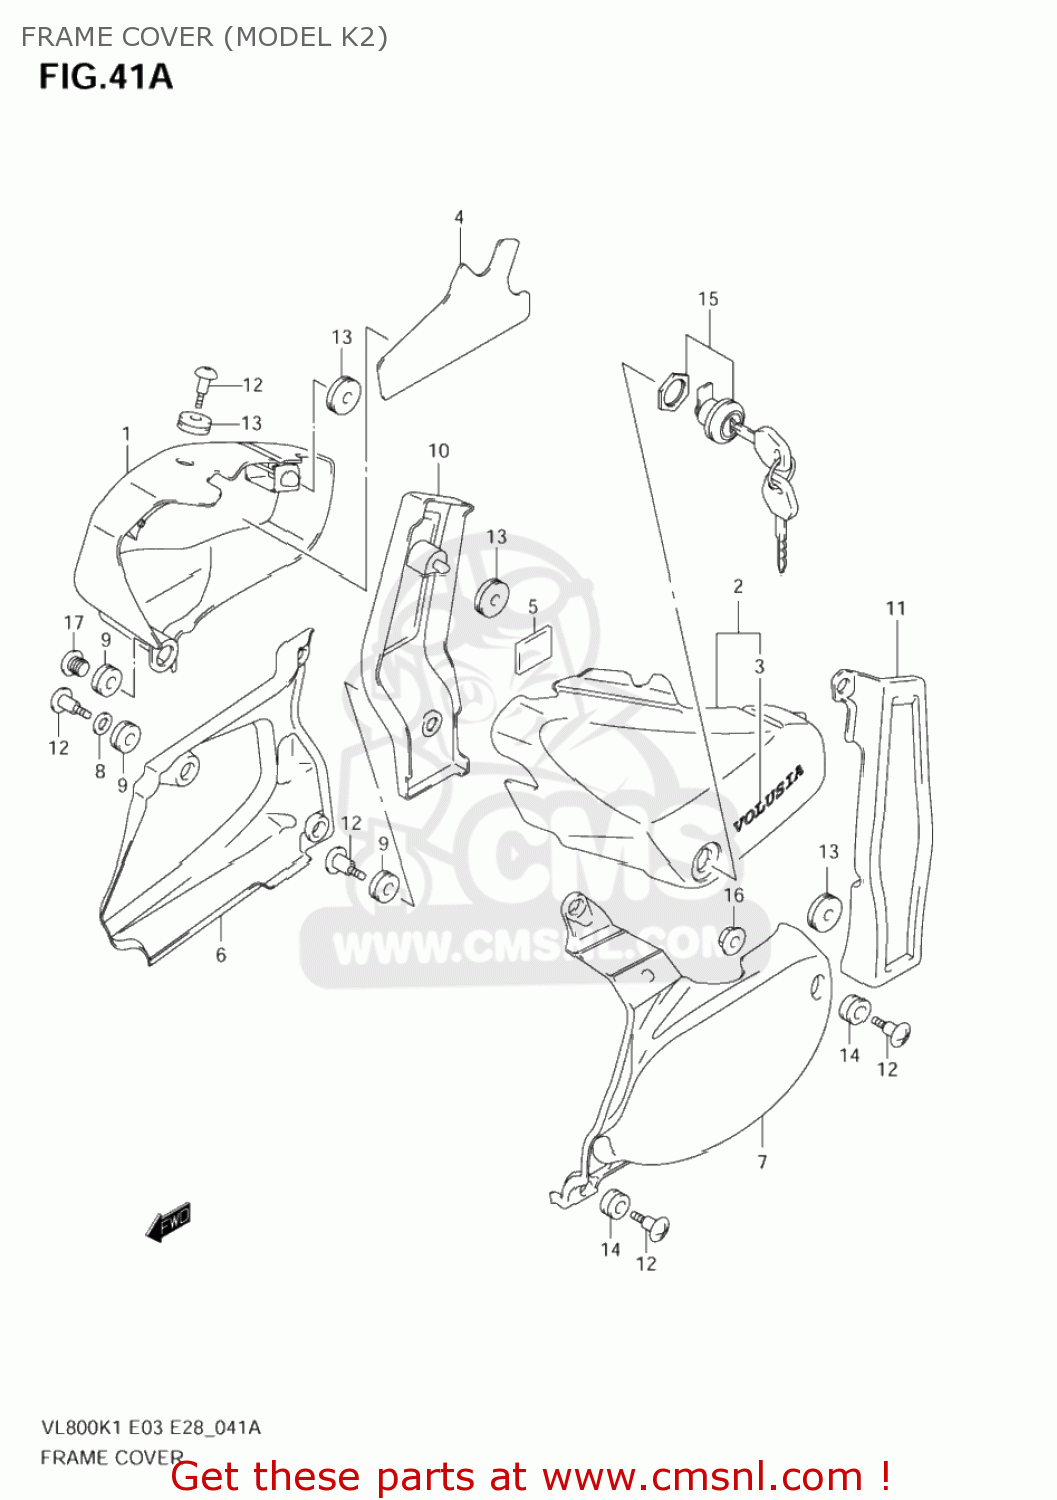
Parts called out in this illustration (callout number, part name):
1	COVER,SIDE,R(BLACK)
2	COVER,SIDE,L(BLACK)
3	EMBLEM,FRAME COVER
4	SHIELD,FRAME COVER
5	PAD,BALANCER UPPER,R
6	COVER,SIDE LWR,R
7	COVER,SIDE LWR,L
8	WASHER(10.5X20X2.3)
9	CUSHION
10	COVER SIDE,REA
11	COVER,SIDE RR,L
12	SCREW(6X20)
13	CUSHION
14	CUSHION
15	LOCK SET,COVER
16	NUT
17	CAP(OD:14)
